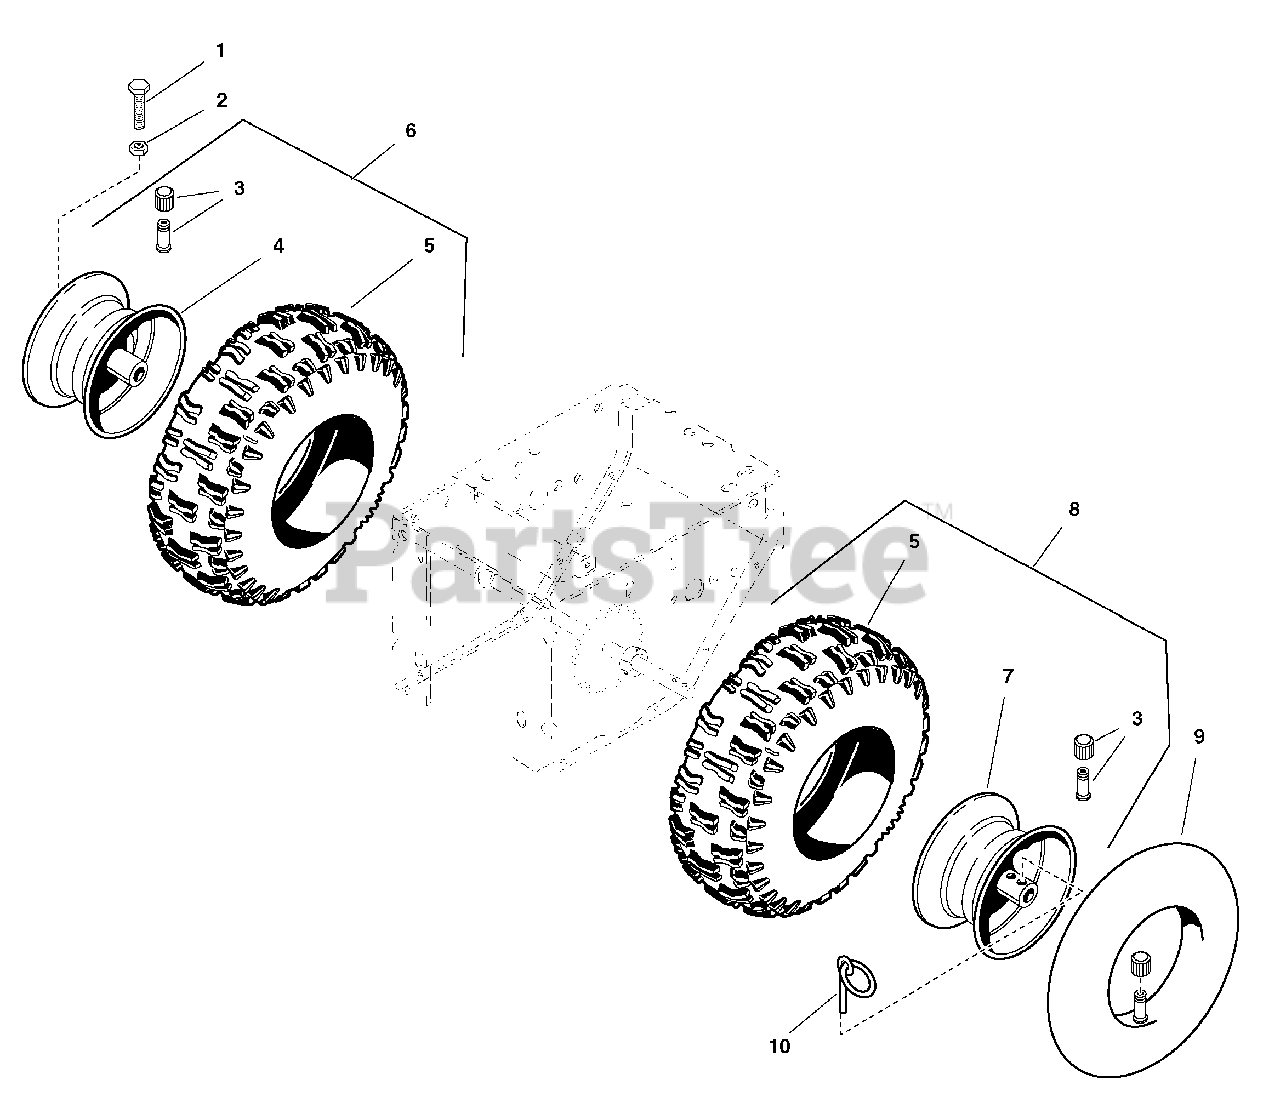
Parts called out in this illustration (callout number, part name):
1	CAPSCREW, Hex Head, 5/16-18 x 2
2	NUT, Hex Lock ESNA Light, 5/16-18
3	VALVE STEM & CAP
4	HUB, Wheel, RH
5	TIRE, 4.80-4.00-8
5	TIRE, 16 x 6.50-6
6	WHEEL & TIRE ASSEMBLY, RH (Includes Ref. Nos. 3, 4 & 5)
7	HUB, Wheel, LH
8	WHEEL & TIRE ASSEMBLY, LH (Includes Ref. Nos. 3, 5 & 7)
9	TUBE, Tire
10	KLIK-PIN
